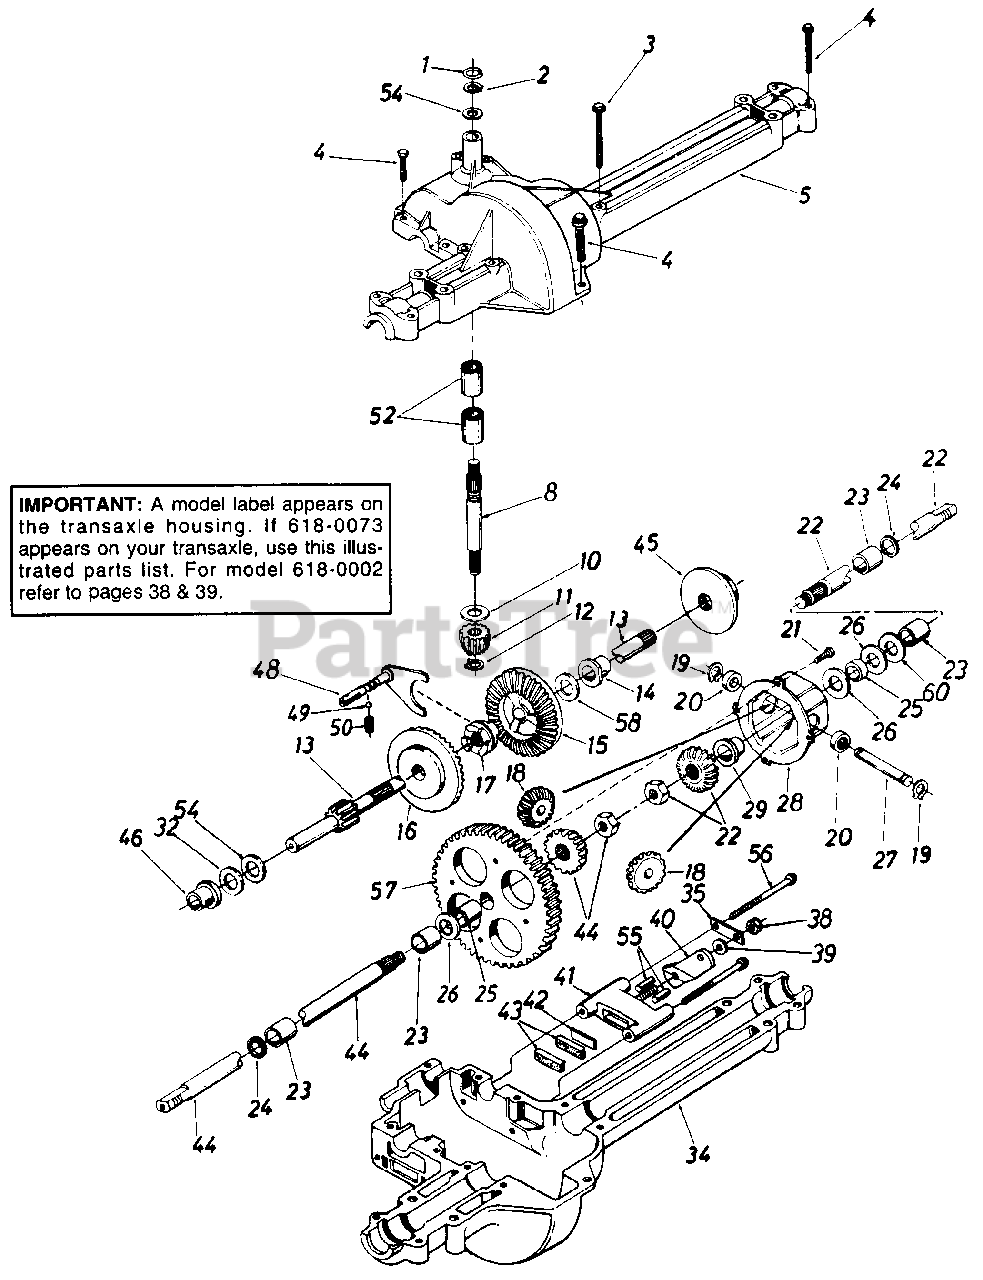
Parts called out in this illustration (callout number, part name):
2	Retaining - Ring
3	Hex Wash. TT-Tap Scr. 1/4-20 x 1.75" Lg.
4	Hex Tap Scr. 1/4-20 x 1.25" Lg.
5	Upper Housing
10	Thrust Washer 5/8" I.D. x 1.25" O.D.
11	Pinion Input 14T
12	Retaining Ring
13	Drive Shaft - R.H. Brake
14	Flange Brg. 5/8" I.D. x 3/4" Lg.
15	Bevel Gear 42T Small I.D.
16	Bevel Gear 42T Large I.D.
17	Clutch Collar
18	Miter Gear 15T (H.D.)
19	Snap Ring
20	Thrust Bearing
21	Pan Head Scr. 1/4-20 x .50" Lg. w/Patch
22	Axle R.H. Ass'y.
23	Sleeve Bearing 3/4" I.D. x 1.0" Lg.
24	Oil Seal 3/4" I.D.
25	Axle Spacer
26	Fl-Wash. .760" I.D. x 1.5" O.D.
28	Differential Can Ass'y.
32	Thrust Wash. 5/8" I.D. x 1" O.D. x .025" Thk.
34	Lower Housing
35	Anti-Rotation Brkt.
38	Hex Nut 5/16-24 Thd.
39	Fl-Wash. .344" I.D. x .875" O.D.
40	Actuating Arm
41	Brake Yoke
42	Puck Plate
43	Brake Puck
44	Axle L.H. Ass'y.
45	Brake Disc
46	Flange Bearing 5/8" I.D. x 15/16" Lg.
48	Shift Fork Ass'y.
49	Ball Detent .250" Dia.
50	Spring Detent
52	Needle Brg. 5/8" I.D. x 1/2" Lg.
54	Fl-Wash. 5/8" I.D. x 1" O.D. x .020 Thk.
55	Actuating Pin 5/16" Dia.
56	Hex Wash Hd. Self-Tap Scr. 1/4-20 Thd.
57	Differential Gear 58T
58	Fl-Wash. 5/8" I.D. x 1" O.D. x .020 Thk.
60	Fl-Wash. .76" I.D. x 1.5" O.D. x .010" Thk.
